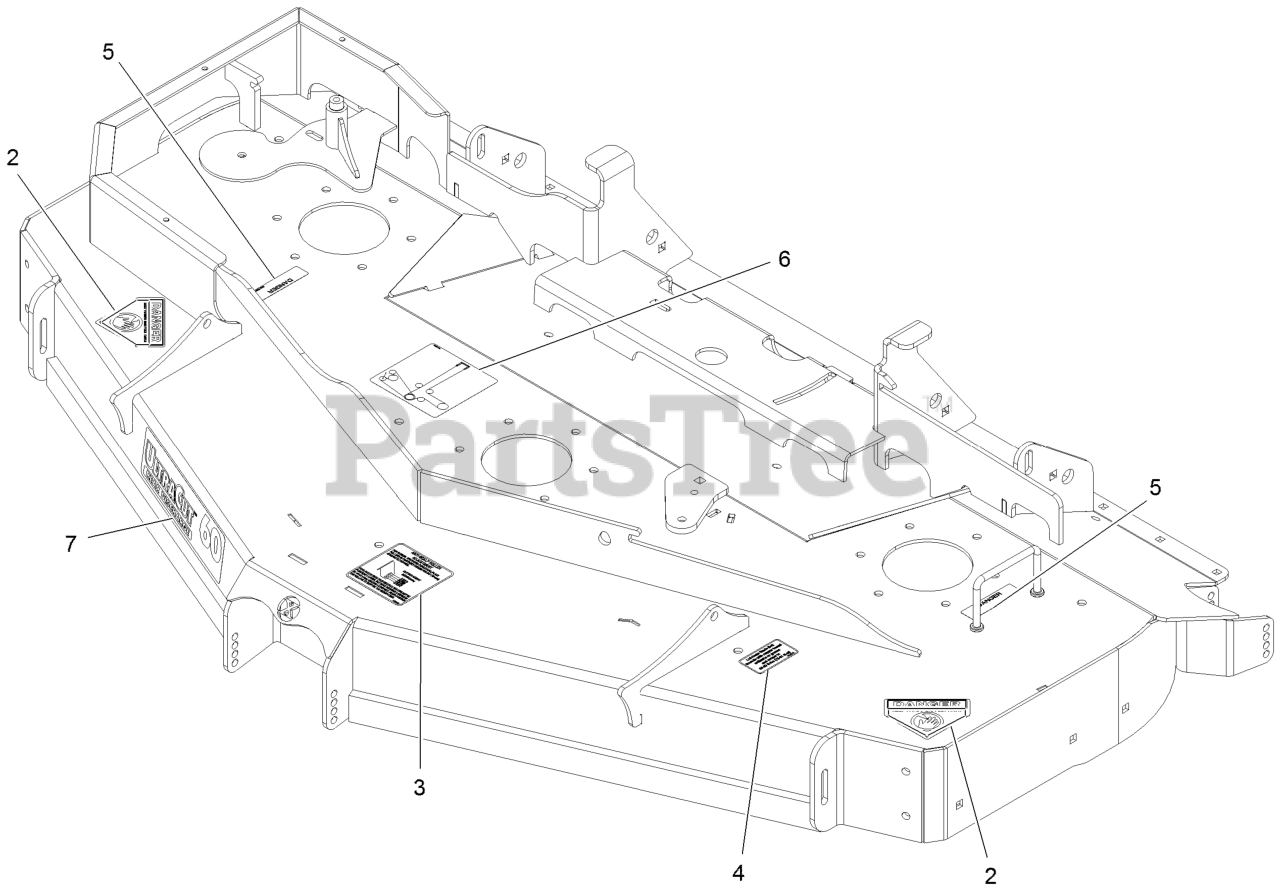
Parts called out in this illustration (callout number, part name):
2	DECAL-DANGER
3	DECAL,ANTISCALP
4	DECAL,BOLT TORQUE
5	DECAL-COVER, MISSING
6	DECAL,BELT ROUTING RD DEC
7	DECAL,REAR DISCHARGE 60
